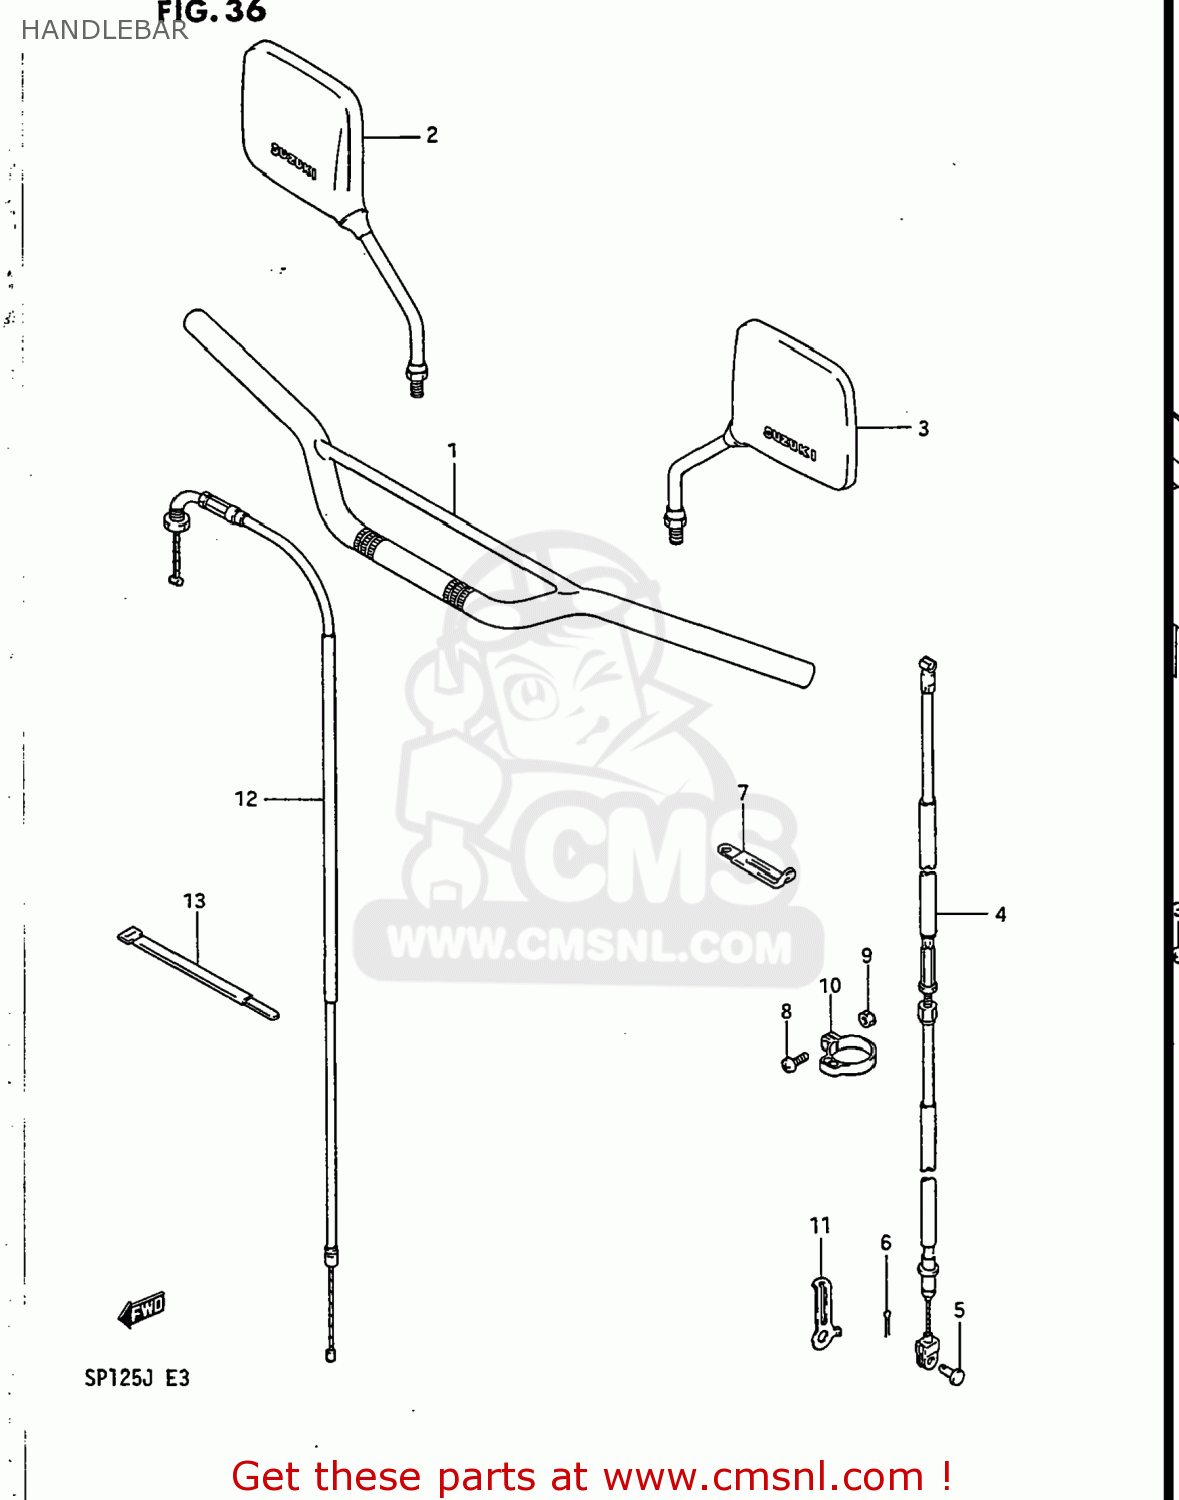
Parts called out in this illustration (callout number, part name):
1	HANDLEBAR
2	MIRROR ASSEMBLY,REAR VIEW
3	MIRROR ASSEMBLY,LEFT
4	CABLE ASSY,CLUTCH
5	PIN(L:15)
6	PIN
7	CLAMP
8	SCREW
9	NUT 5MM
10	CLAMP,CABLE
11	CLAMP,CABLE
12	CABLE ASSY,THROTTLE
13	CLAMP
